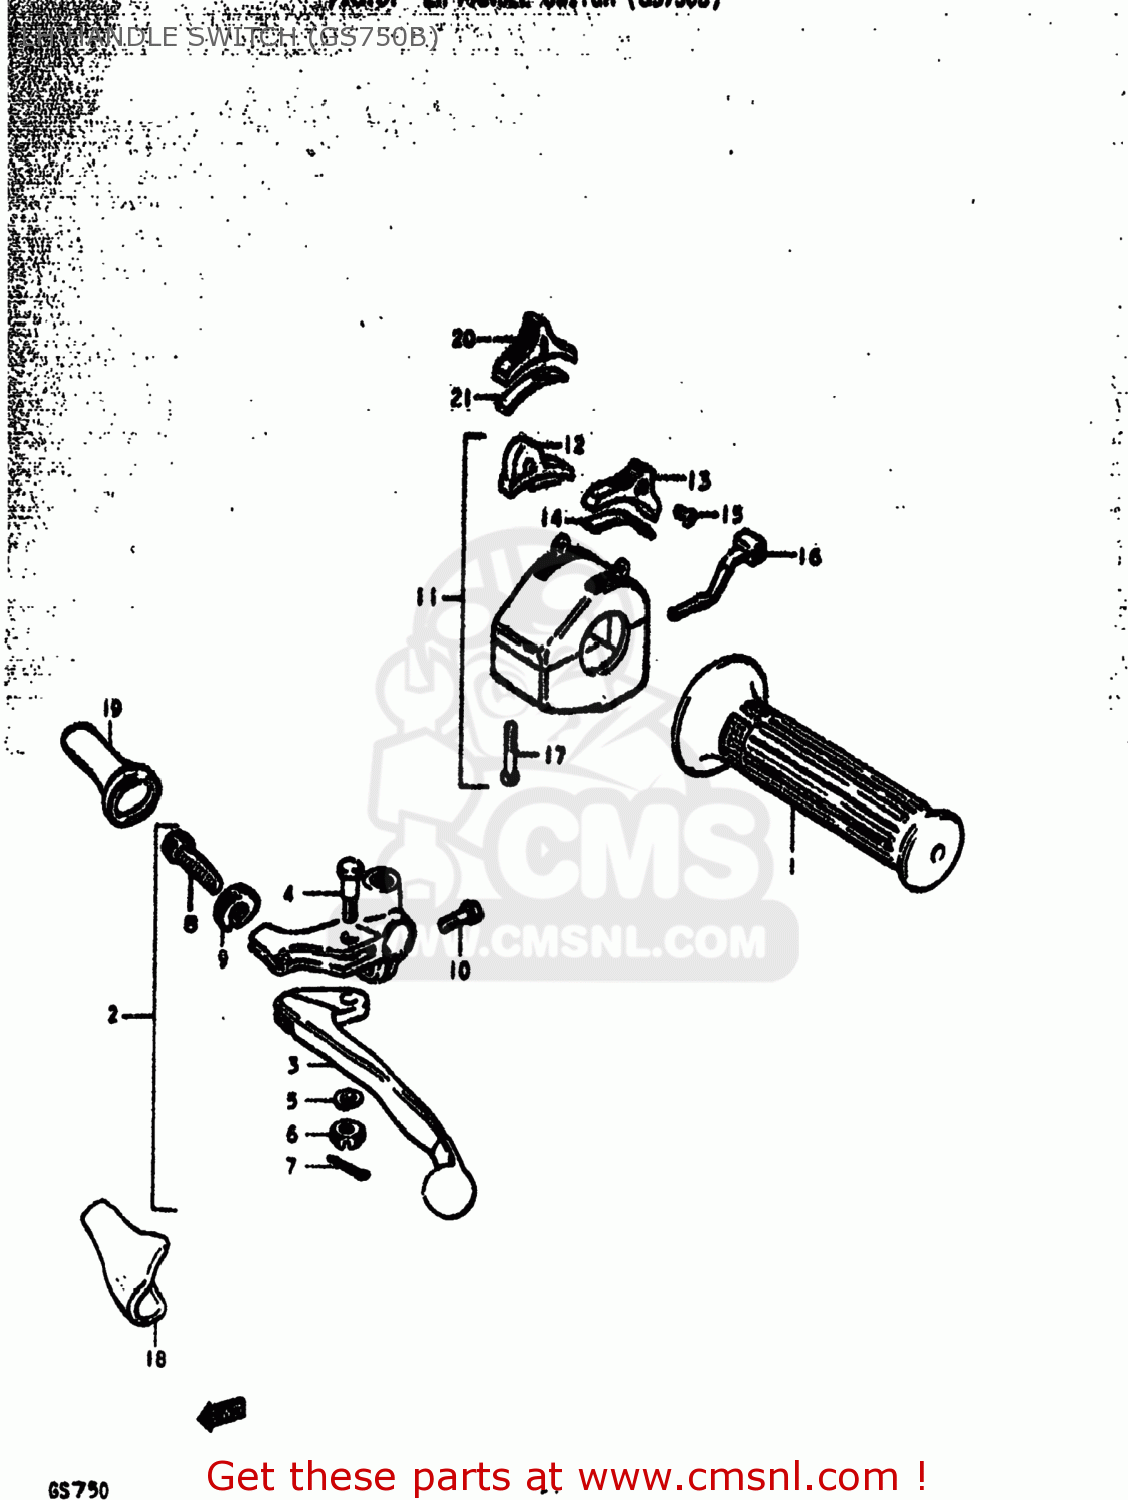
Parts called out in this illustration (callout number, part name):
1	GRIP,LEFT
2	LEVER ASSY,CLUTCH
3	LEVER,CLUTCH
4	BOLT,LEVER
5	LOCK WASHER
6	NUT,LEVER FITTNG
7	COTTER PIN
8	ADJUSTER,CABLE
9	NUT,CABLE ADJUSTER
10	BOLT
11	SWITCH ASSEMBLY,HANDLE,LEFT
13	KNOB,HANDLE SWITCH
14	PLATE,SWITCH KNOB
15	SCREW
16	KNOB,TURN SIGNAL SWITCH
17	SCREW
18	COVER,CLUTCH LEVER
19	BOOT,CLUTCH CABLE
20	KNOB,HANDLE SWITCH
21	PLATE,SWITCH KNOB
